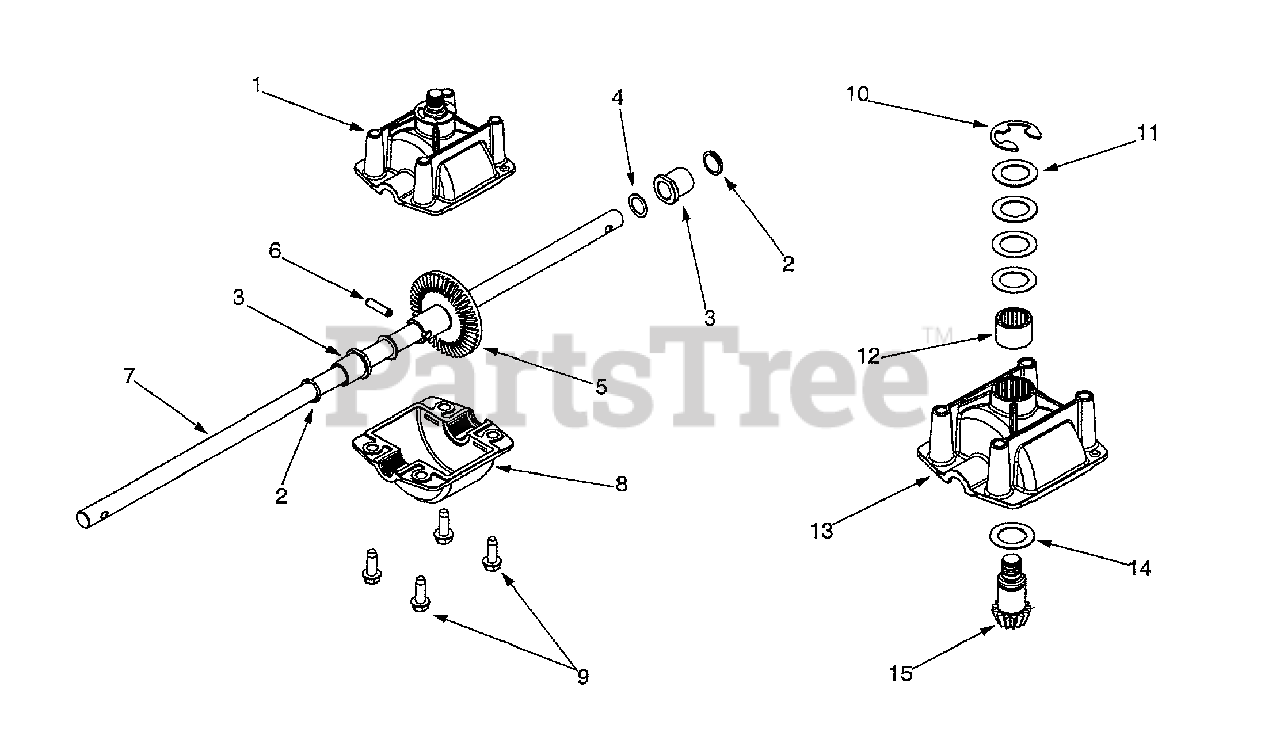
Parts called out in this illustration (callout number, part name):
1	Upper Housing Assembly
2	Oil Seal .500 ID x .687 OD
3	Flange Bearing .503 ID x .689 OD
4	Flat Washer .504 ID x .700 OD x .030
5	Bevel Gear 44T
6	Roll Pin
7	Output Shaft
8	Lower Housing
9	Hex Washer Screw 1/4-20 x .75
10	E-Ring .750
11	Flat Washer .625 ID x 1.0 OD x .030
12	Needle Bearing .625 x .813
13	Upper Housing
14	Flat Washer .625 ID x 1.0 OD x .030
15	Input Shaft
